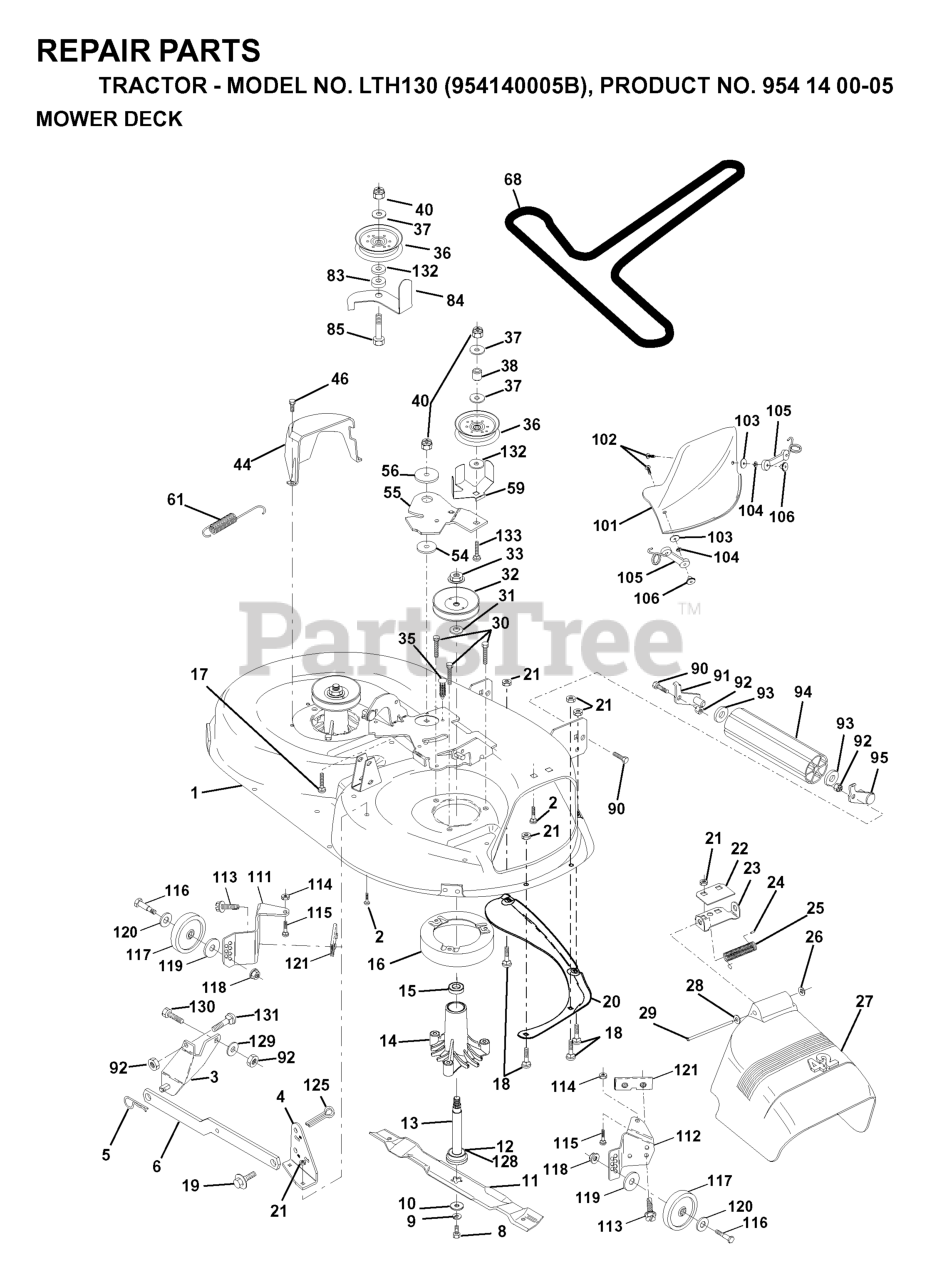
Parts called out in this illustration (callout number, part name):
1	DECK 42"
2	RP BOLT 5/16-18 X3/4 ZN/YEL GR
3	BRKT ASM SWAY BAR
4	BRKT DECK SW BAR
5	RETAINER-SPRNG RB
6	REAR SUSP ARM
8	BLADE BOLT
9	LOCKWASHER
10	WASHER.BLADE
11	BLADE.42".MULCH
12	BEARING.BALL.#6204.(MANDREL)
13	SHAFT ASM VENT
14	HOUSING.MANDREL.VENTED (MACHD)
16	STRIPPER
17	BOLT CARRIAGE
18	BOLT
19	BOLT SHD 5/16-18
20	BAFFLE
21	LOCKNUT
22	STIFFENER BRACKET
23	DEFLECTOR BRACKET
24	CAP-SLEEVE LT
25	SPRING TORSION
26	NUT PUSH M
27	SHIELD.DEFLECTOR.MOWER.42".BLK
28	Washer 11/32 x 5/8 x 16 Ga SD
29	ROD.HINGE
30	SCREW THDROL ROLLING WASHER HD
31	WASHER
32	PULLEY/MANDREL
33	NUT
35	FASTENER.XMAS.TREE
36	FLAT IDLER PULLEY
37	WASHER
38	IDLER SPRING SPACER
44	GUARD MANDREL LH BLACK
46	SCREW.1/4-20X5/8
54	HARDENED WASHER
55	IDLER ARM
56	SPACER RETAINER
59	GUARD, BELT
61	SPRING EXTENSION
68	V-BELT TRIPATH
84	KEEPER.BELT.IDLER
85	BOLT
90	BOLT
91	BRACKET LH (A)
92	NUT
93	Washer 1 17/32 X 7/8 X 16 Ga
94	NOSE ROLLER
95	BRACKET RH (B)
101	COVER MULCH 42"
102	SCREW
104	LOCKWASHER #10
105	LATCH ASSEMBLY
106	WELDNUT
111	BRACKET WHEEL GAUGE LH 42" DK
112	BRACKET WHEEL GAUGE RH 42" DK
113	SCREW.THDROL.5/16-18X3/4.TTY
114	NUT
115	BOLT.CARR.5/16-18X1/2
116	BOLT M
117	WHEEL.GAUGE.BLK.4.93
118	LOCKNUT
119	WASHER.5/16.FLAT.STE.STD.
120	Washer 17/32 x 15/16 x 12 Gauge
121	BRACKET.EXTRUDED.GAGE.WHEEL
125	Pin Cotter 1/4 x 1 Plated
128	WASHER FELT
129	WASHER
131	BOLT D
132	Washer 13/32 x 1-3/8 x 13 Ga.
